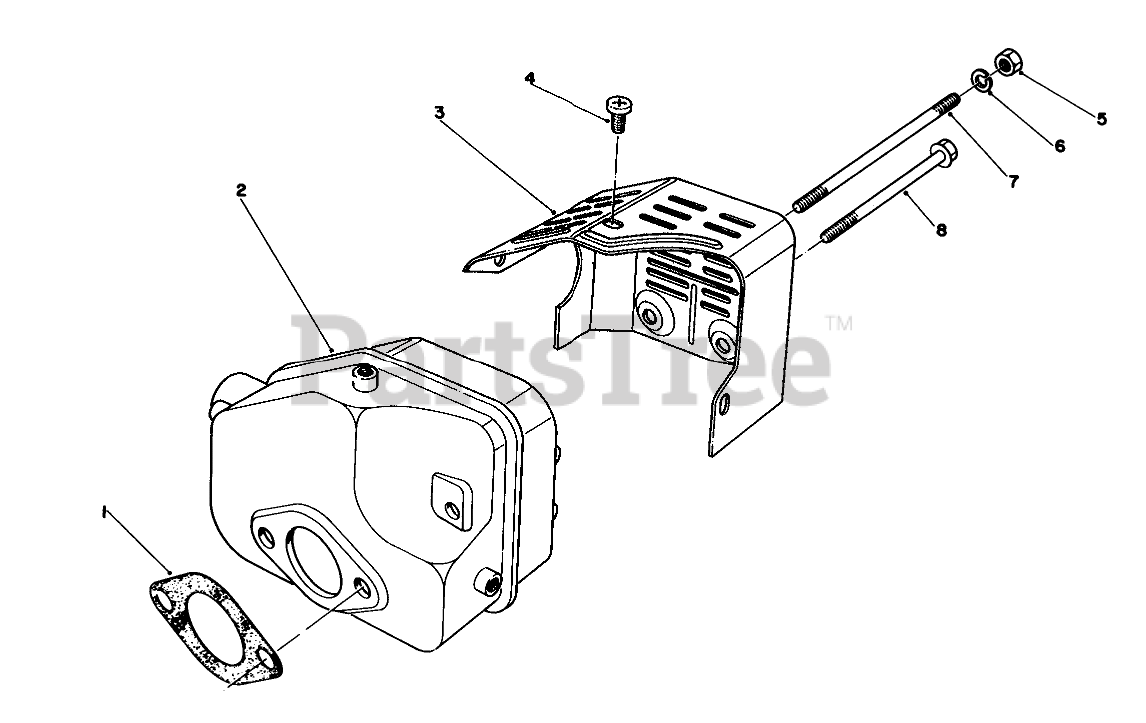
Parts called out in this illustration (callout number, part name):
1	GASKET
2	Muffler
3	COVER
4	SCREW
6	WASHER-LOCK
